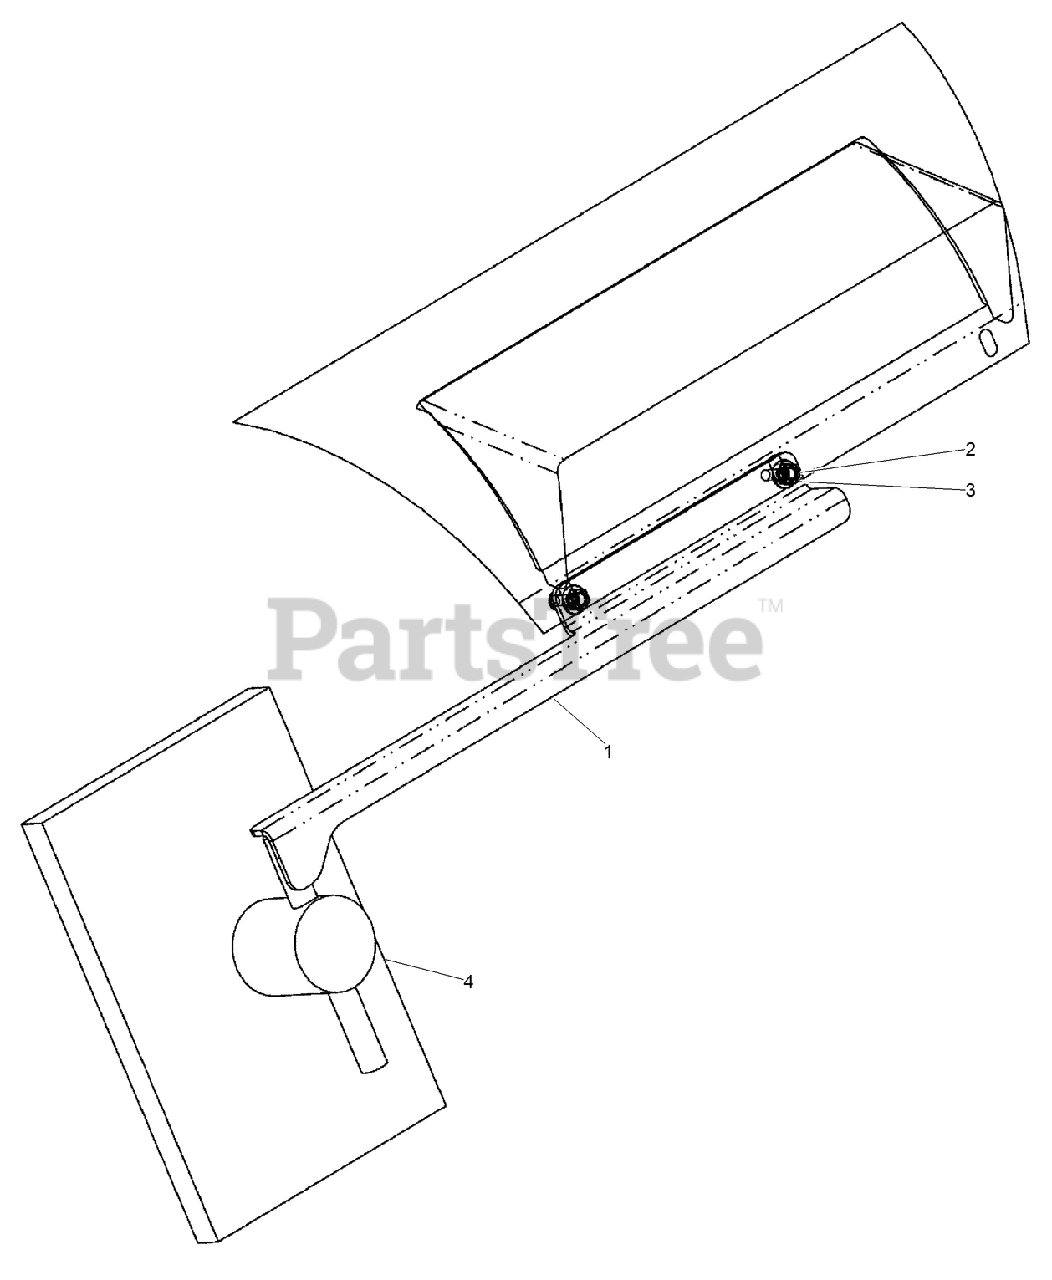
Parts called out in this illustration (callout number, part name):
1	WELDMENT - Mirror Mount
2	SCREW-FLANGE
3	NUT-FLANGE, NYLOCK
4	MIRROR
